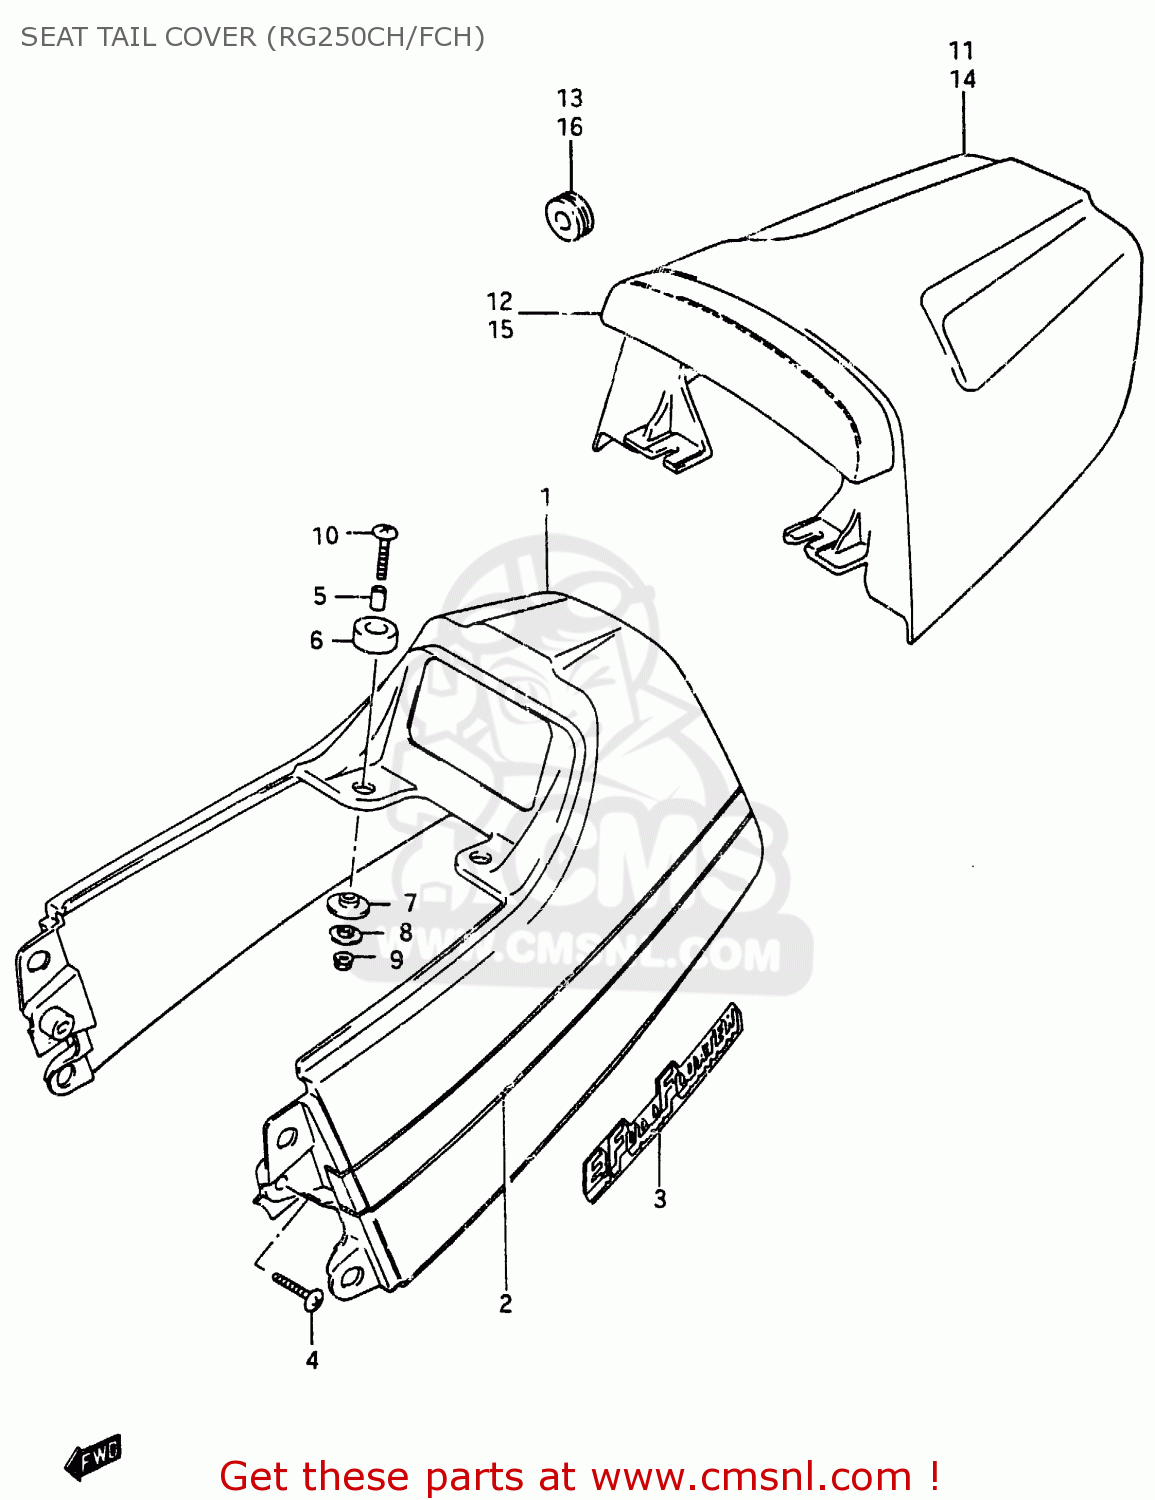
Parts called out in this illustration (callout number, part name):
1	COVER, SEAT TAIL
2	TAPE SET, SEAT TAIL COVER
3	EMBLEM
4	SCREW
5	SPACER (6.1X8X12)
6	CUSHION,COVER
7	CUSHION,SEAT TAIL COVER LWR
8	WASHER
9	NUT
10	SCREW
11	BOX SET, SEAT TAIL (RED)
12	BACKREST, SEAT (RED)
13	CUSHION
14	BOX SET, SEAT TAIL (RED)
15	BACKREST, SEAT (RED)
16	CUSHION
